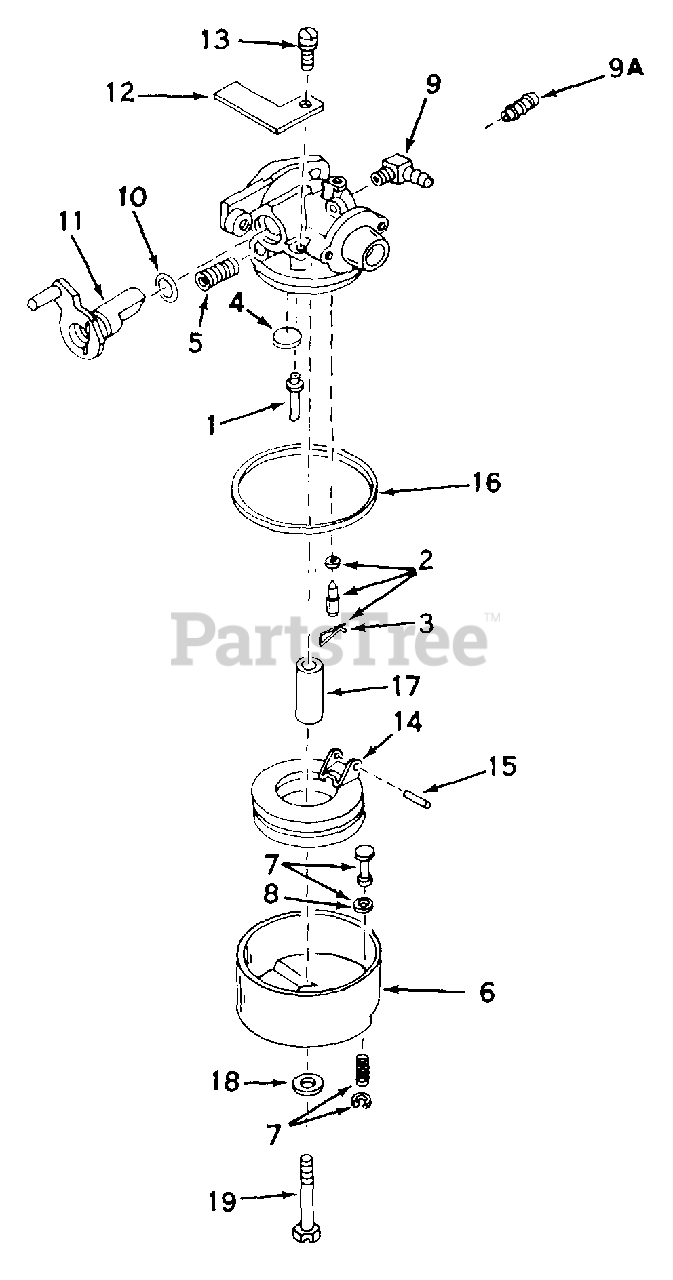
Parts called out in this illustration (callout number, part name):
1	"Tube, Fuel pickup
2	Inlet Needle & Spring Assy.
3	Spring, Inlet needle
4	Plug, Welch
5	Spring, Positioning
6	Bowl, Float
7	Plunger Assy., Drain
8	Gasket, Drain plunger
9	Fitting, Fuel
10	"O" Ring
11	Valve, Control
12	Plate, Retaining
13	Screw, Fil. hd. Sems, 8-32 x 3/8
14	Float, Carburetor
15	Shaft, Float
16	Gasket, Bowl-to-body
17	Spacer, Bowl
18	Washer, Fiber
19	Screw, Hex slotted hd. mach., 10-24 x 1-1/4
